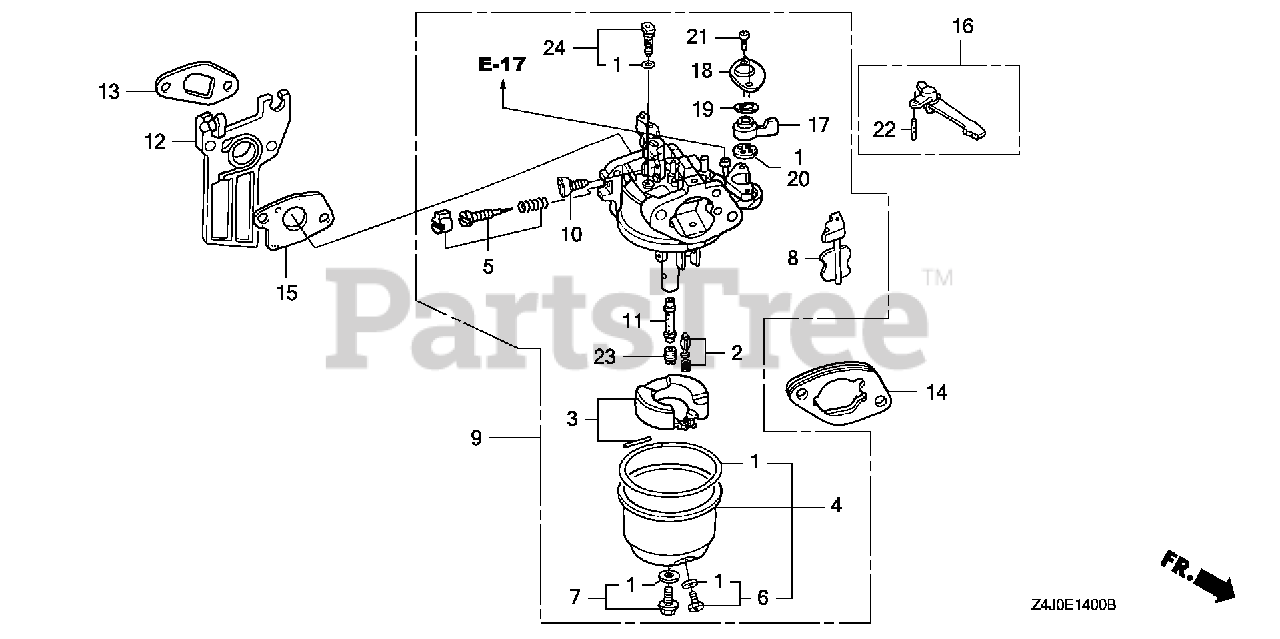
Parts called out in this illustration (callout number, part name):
1	GASKET SET (CARBURETOR NO.)
2	VALVE SET, FLOAT (CARBURETOR NO.) (SEAT NOT INCLUDED)
3	FLOAT SET
4	CHAMBER SET, FLOAT (CARBURETOR NO.)
5	SCREW SET (Honda Code 4219879). (CARBURETOR NO.)
6	SCREW SET, DRAIN (Honda Code 1672187). (CARBURETOR NO.)
7	SCREW SET B
7	SCREW SET
8	CHOKE SET
9	CARBURETOR ASSY. (BE66D B)
10	SCREW, THROTTLE STOP
11	NOZZLE, MAIN
12	INSULATOR, CARBURETOR
13	GASKET, INSULATOR
14	SPACER, CARBURETOR
15	GASKET, CARBURETOR
16	LEVER, CHOKE (STD)
17	LEVER, VALVE
18	PLATE, LEVER SETTING (CARBURETOR NO.)
19	SPRING, PETCOCK LEVER (CARBURETOR NO.)
20	GASKET, VALVE
21	SCREW, PAN (3X6)
22	PIN, SPRING (2X12)
23	JET, MAIN (#65)
23	JET, MAIN (#68)
23	JET, MAIN (#70)
24	JET SET, PILOT (#35)
